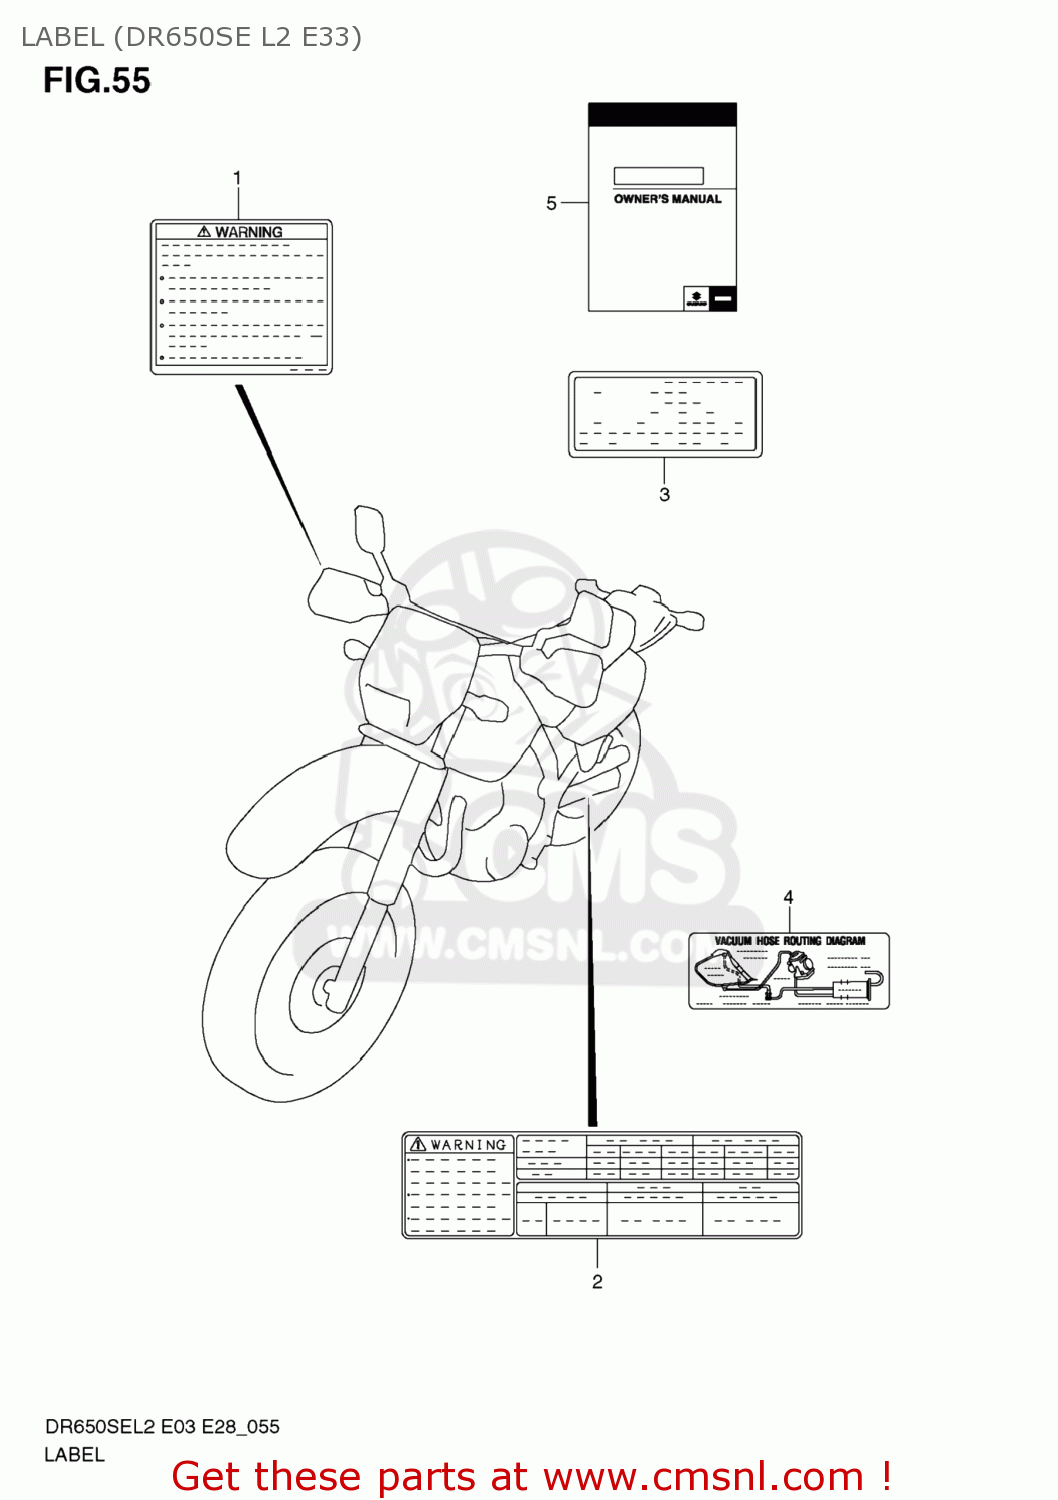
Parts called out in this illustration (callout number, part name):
1	LABEL,GENERAL WARNING
2	LABEL,TIRE INFORMATION
3	LABEL,MANUAL NOTICE
4	LABEL,PIPING DIAG
5	MANUAL,OWNER'S
